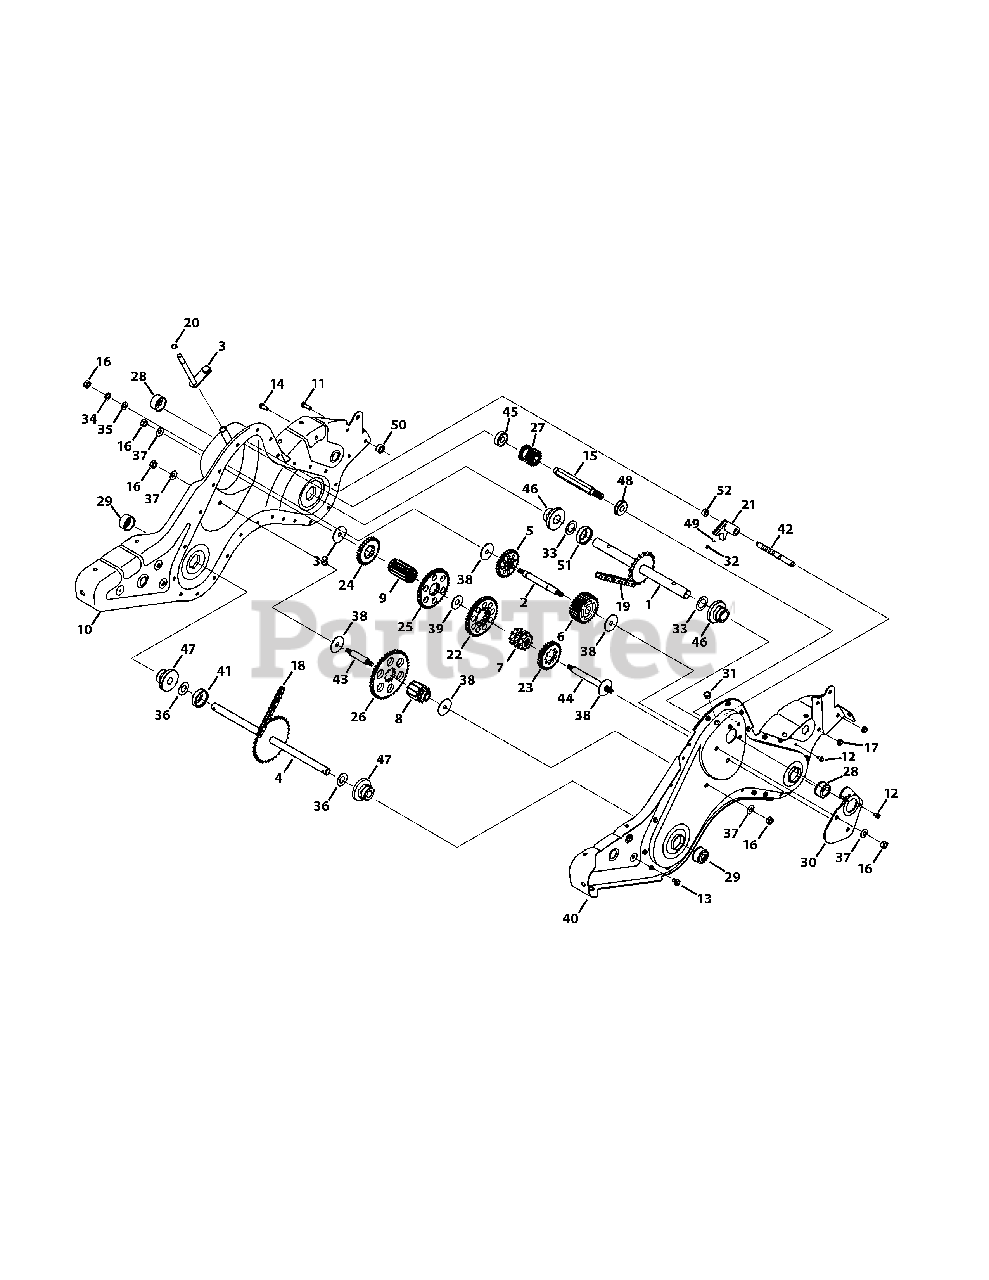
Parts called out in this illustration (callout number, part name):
1	Tine Shaft Assembly
2	Jack Shaft Assembly
3	Shift Input Shaft Assembly
4	Wheel Shaft Assembly
5	Reverse Idler Gear Assembly
6	Tine Idler Gear Assembly
7	Tine Input Sprocket Assembly
8	Wheel Input Sprocket Assembly
9	Gear Assembly
10	RH Chain Case Housing Assembly
11	Hex Screw, 5/16-18 x 1.00
12	Screw, 1/4-20 x 0.500
13	Screw, 5/16-18 x 0.625
14	Hex Screw, 5/16-18 x .75
15	Input Shaft, .75
16	Hex Nut, 7/16-20
17	Flange Lock Nut, 5/16-18
18	Endless Chain, 420 x 50
19	Endless Chain, 50 x 54
20	Snap Ring, .500
21	Clutch Collar
22	Gear Spur, 44T
23	Gear Spur, 30T
24	Gear Spur, 30T
25	Gear Spur, 44T
26	Gear Spur, 44T
27	Gear Spur, 16T
28	Shaft Seal, 1.0
29	Shaft Seal, .75
30	Positioner Gear Bracket
31	Tapered Cap Plug
32	Compression Spring, .230
33	Flat Washer, 1.03 x 1.62 x .03
34	Lock Washer, 7/16
35	Flat Washer, .474 x .879 x .064
36	Flat Washer, .760 x 1.50
37	Bell Washer,.45 x 1.00 x .062
38	Thrust Washer, .445 x 1.92 x .060
39	Flat Washer, 1.595 x .635 x .062
40	LH Chain Case Housing
41	Spacer, .75 x 2.0 x .50
42	Shaft Detent, .5
43	Jack Shaft, .625 x 2.385
44	Jack Shaft, .6250 x 5.0050
45	Ball Bearing, 17 x 40 x 12
46	Flange Bearing, 1.0 x 2.5 x 1.38
47	Flange Bearing, .75 x 2.5 x 1.38
48	Ball Bearing, 17 x 40 x 12:6203
49	Detent Ball, .250
50	Spacer, .315 x .750 x .375
51	Spacer, 1.0 x 2.0 x .5
52	Spacer, .505 x .88 x .440
